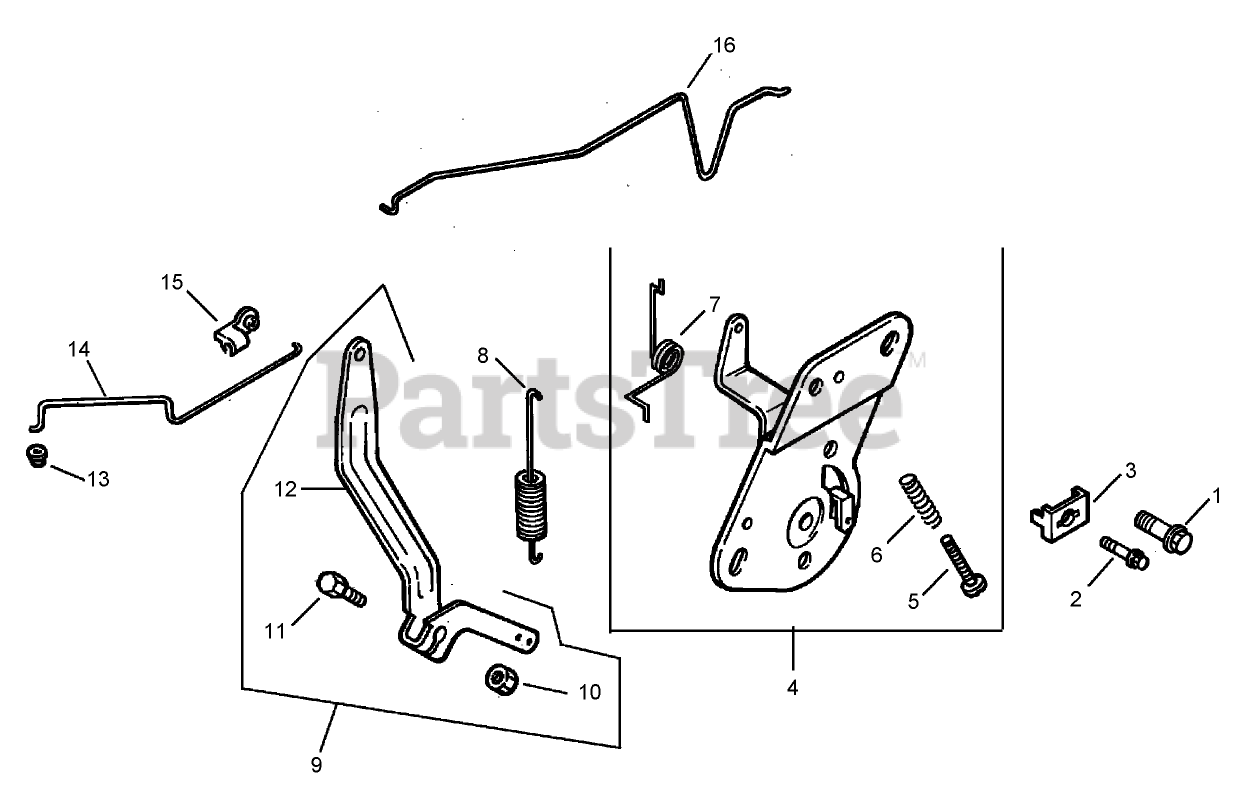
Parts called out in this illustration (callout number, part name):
1	Screw-Socket, 6 Lobed (Thread Forming, M6x1.0x20)
2	SCREW-FLANGE, THREAD FORMING (M5X0.8X16)
3	CLAMP-CABLE
4	Speed Control ASM (Includes 5-7)
5	Screw-Pan Head (w/loctite)
6	Spring-Control, Speed
7	Spring-Return, Choke
8	Spring-Governor
9	Governor Lever Kit (Includes 10-12)
10	Nut-Flange, Hex (1/4-20)
11	Bolt-Square Neck, Round Head (1/4-20x1)
12	Lever-Governor
13	BUSHING-LINKAGE, THROTTLE
14	Linkage-Throttle
15	BUSHING-RETAINING, LINKAGE
16	Linkage-Choke
